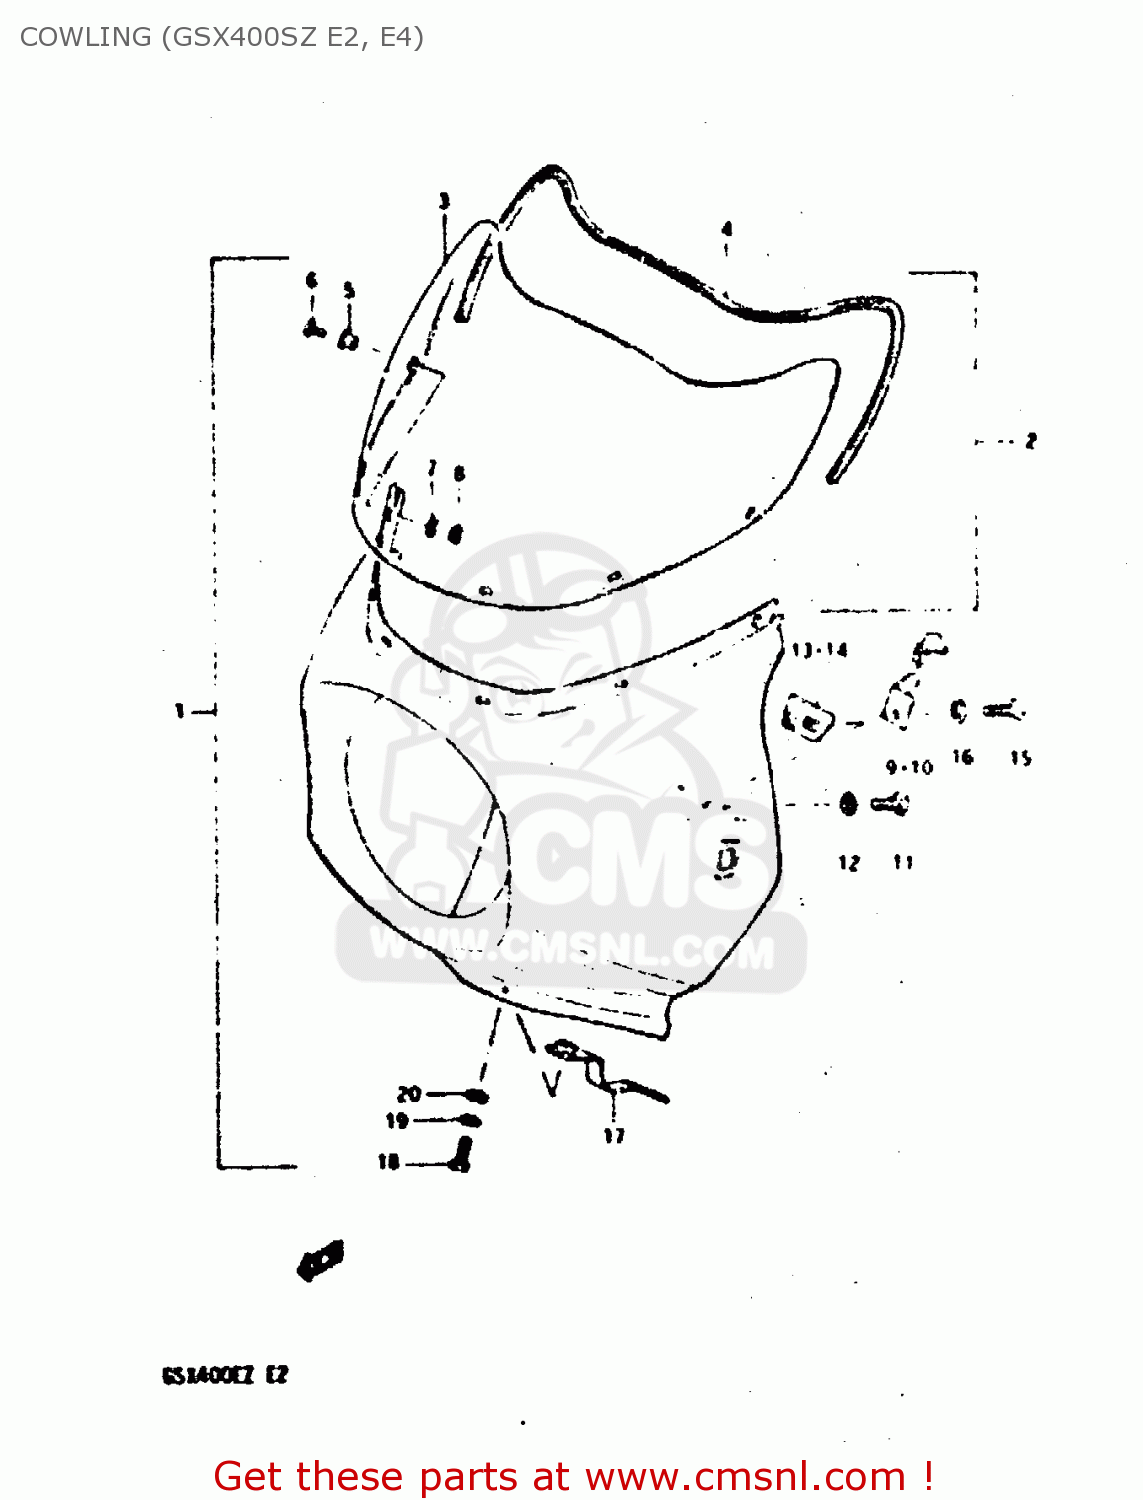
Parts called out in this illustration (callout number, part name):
1	COWLING ASSY (RED)
2	COWLING ASSY
3	WINDOW
4	MOULDING
5	CUSHION
6	SCREW
7	WASHER
8	NUT
9	BRACKET,COWLING RH
10	BRACKET,COWLING LH
11	BOLT
12	LOCK WASHER
13	BRACKET, FITTING RH
14	BRACKET, FITTING LH
15	BOLT, UPPER
16	WASHER (6.5X18X1.6)
17	BRACKET, LOWER
18	BOLT
19	LOCK WASHER
20	WASHER
